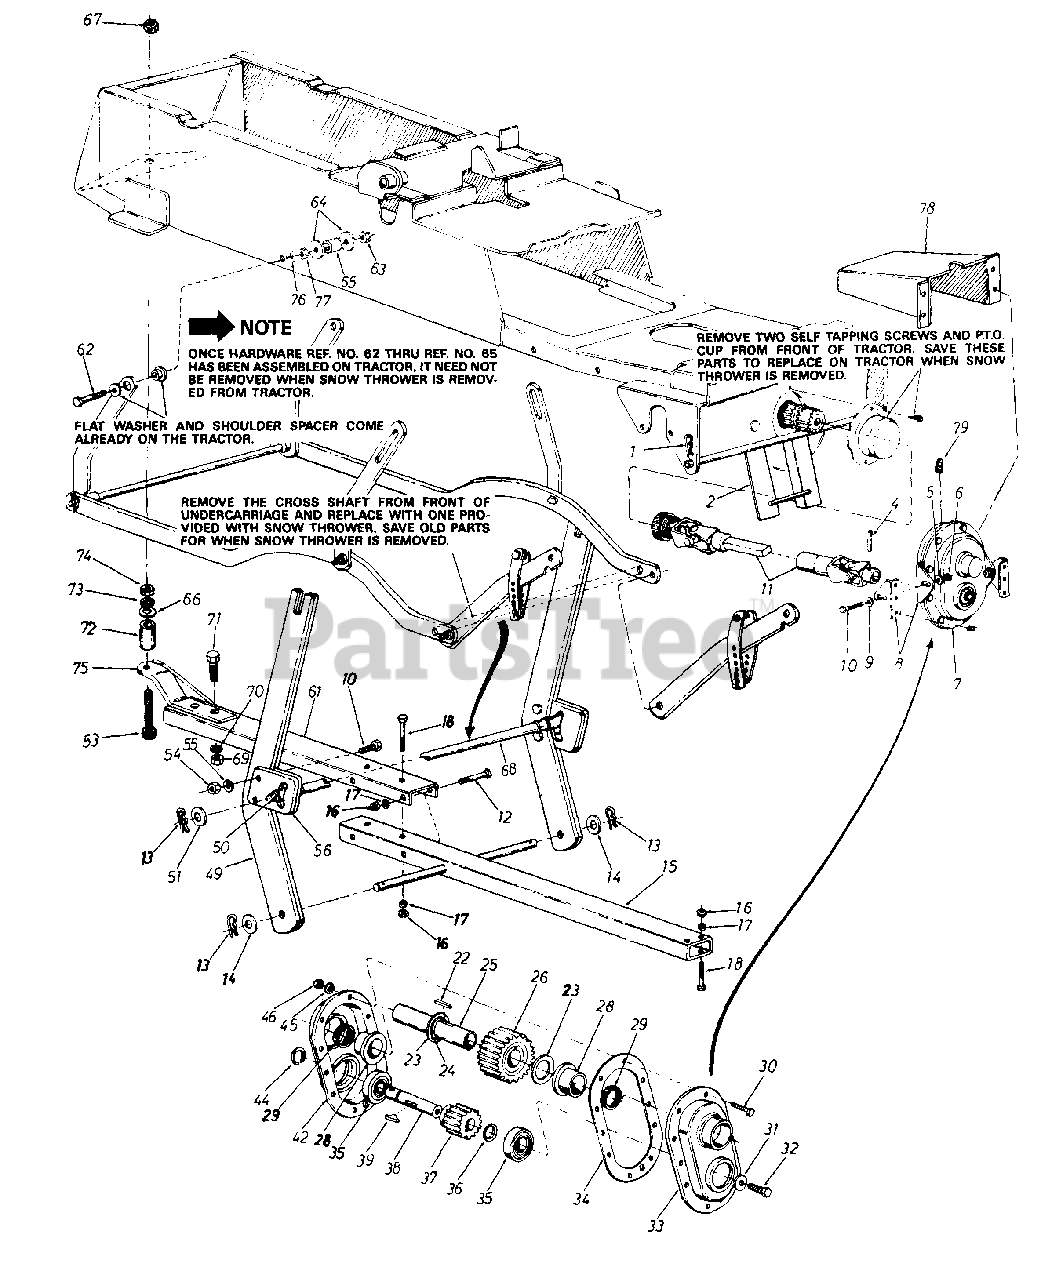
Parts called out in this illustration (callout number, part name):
1	Intern. Cotter Pin 3/4" Dia.
2	Guide Bracket Ass'y.
4	Roll Pin Spirol 5/16" Dia. x 2.5" Lg.
5	Belleville Wash..341" I.D. x .88" O.D.
6	Hex Nut 5/16-18 Thd.
7	Gear Box Ass'y. Comp.
8	Gear Box Support Brkt.
9	Belleville Wash..341" I.D. x .88" O.D.
10	Hex Bolt 5/16-18 x 1.25" Lg. (Grade 5)
11	Universal Drive Shaft Ass'y.
12	Hex Bolt 3/8-24 x 4.50" Lg.
13	Hair Pin Cotter
14	Fl.-Wash..75" I.D. x 1.5" O.D.
15	Lift Shaft Ass'y.
16	Hex Ins. Jam L.-Nut 3/8-24 Thd.
17	L.-Wash. 3/8" I.D.
18	Hex Bolt 3/8-24 x 2.75" Lg.
22	Hi-Pro Key 1/4" x 7/8" Dia.
23	Fl.-Wash. 1.31" I.D. x 2.00" O.D. x .060
24	Snap Ring for 1.25" Dia. Shaft
25	Gear Shaft 1.25" Dia. x 6.0" Lg.
26	28 Teeth Spur Gear
28	Flange Bearing 1.25" I.D. x 1.75" O.D.
29	Oil Seal 1.25" I.D. x 1.75" O.D. x .26
30	Hex Bolt 1/4-28 x .88" Lg.
31	Fl.-Wash..40" 1.0. x 1.25" O.D. x .160
32	Hex L.-Bolt 3/8-24 x 1.00" Lg.
33	Gear Housing Half - L.H.
34	Gasket
35	Ball Bearing 1.00" I.D. x 2.00" O.D.
36	Fl.-Wash. 1.03" I.D. x 1.63" x .090
37	15 Teeth Spur Gear
38	Input Shaft
39	Woodrull Key 1/4" x 3/4" Dia.
42	Gear Housing Half-R.H.
44	Snap Ring for 1.00" Dia. Shaft
45	Spring Wash. 1/4" I.D.
46	Hex Nut 1/4-28 Thd.
51	FI.-Wash..62" I.D. x 1.12" O.D.
53	Hex Bolt 5/8-11 x 4.00" Lg.
54	Hex Nut 5/l6-18 Thd.
55	L.-Wash. 5/16" I.D.
62	Hex Bolt 3/8-24 x 2.50" Lg. (Grade 5)
63	Hex Jam L.-Nut 3/8-24 Thd.
64	Fl.-Wash..375" I.D. x 1.00" O.D. x .135"
65	Spacer .375" I.D. x .625" O.D. x .445
66	Fl.-Wash..62" I.D. x 1.12" O.D.
67	Hex Jam L.-Nut 5/8-11 Thd.
68	Cross Shaft Ass'y.
69	Hex Nut 1/2 -13 Thd.
70	L.-Wash. 1/2" I.D.
71	Hex Bolt 1/2-13 x 1.25" Lg.
72	Spacer .65" I.D. x 2.12" Lg.
73	E.-Wash. 5/8" I.D."
74	Hex Jam Nut 5/8-11 Thd.
77	Hex Nut 3/8-24 Thd.
78	Drive Shaft Cover
79	Grease Fitting
